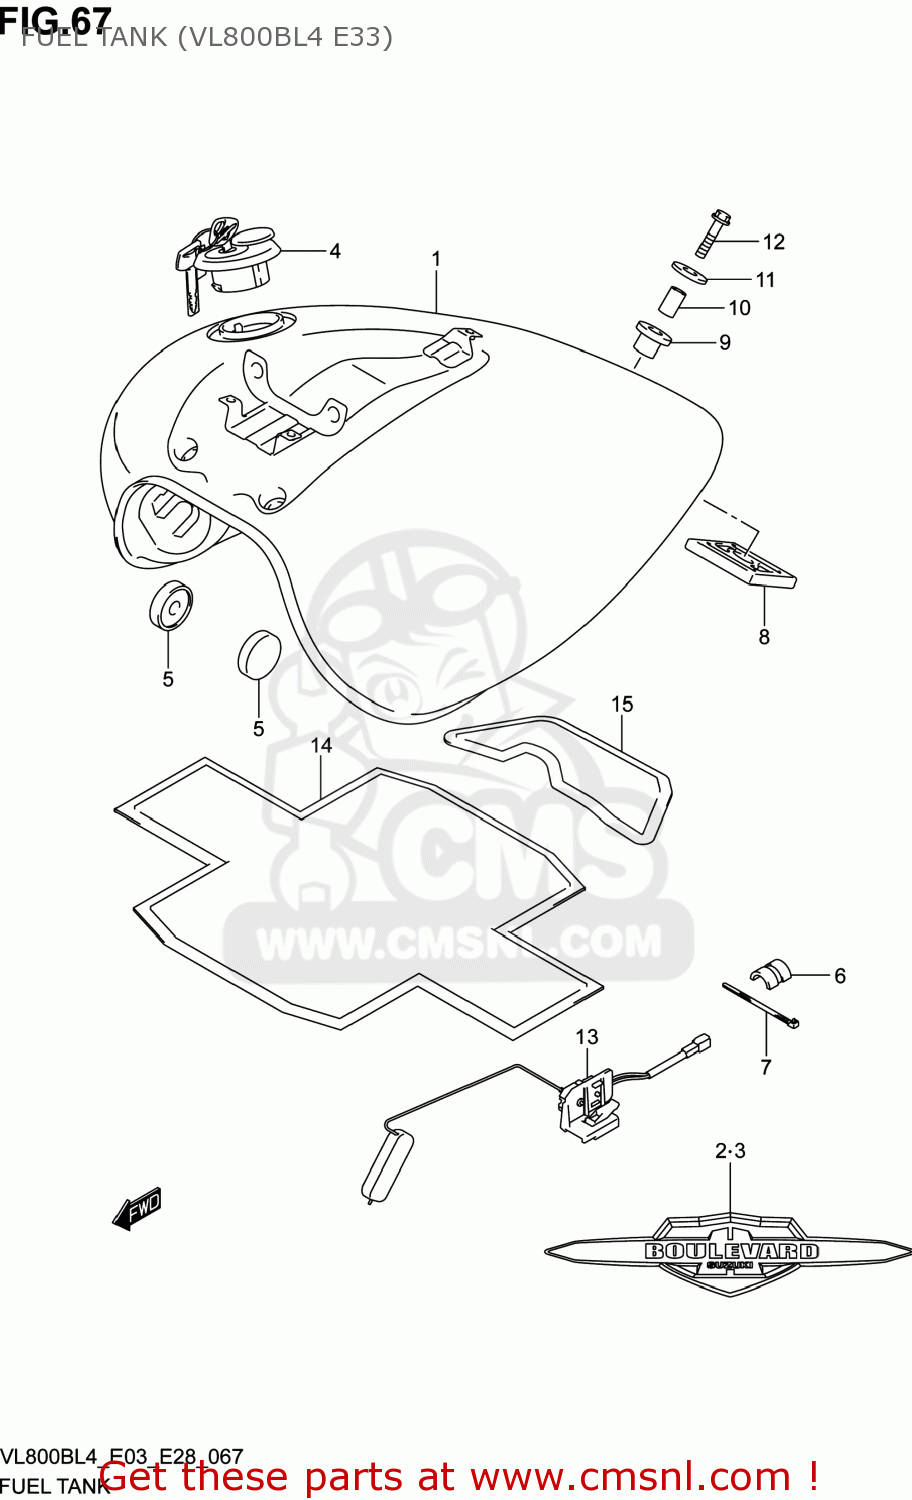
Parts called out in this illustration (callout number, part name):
1	TANK ASSY,FUEL(BLACK)
2	EMBLEM,FUEL TANK,R
3	EMBLEM,FUEL TANK,L
4	CAP SET,FUEL TANK
5	CUSHION
6	CUSHION,FUEL TANK LWR
7	CLAMP(L:250)
8	CUSHION,FUEL TANK RR LWR
9	CUSHION,FUEL TANK RR UPR
10	SPACER (8.2X12.5X23.5)
11	WASHER(8.5X33X1.5)
12	BOLT
13	GAUGE ASSY,FUEL LEVEL SENDER
14	SHIELD,FUEL TANK HEAT
15	SHIELD,FUEL TANK HEAT NO.2
